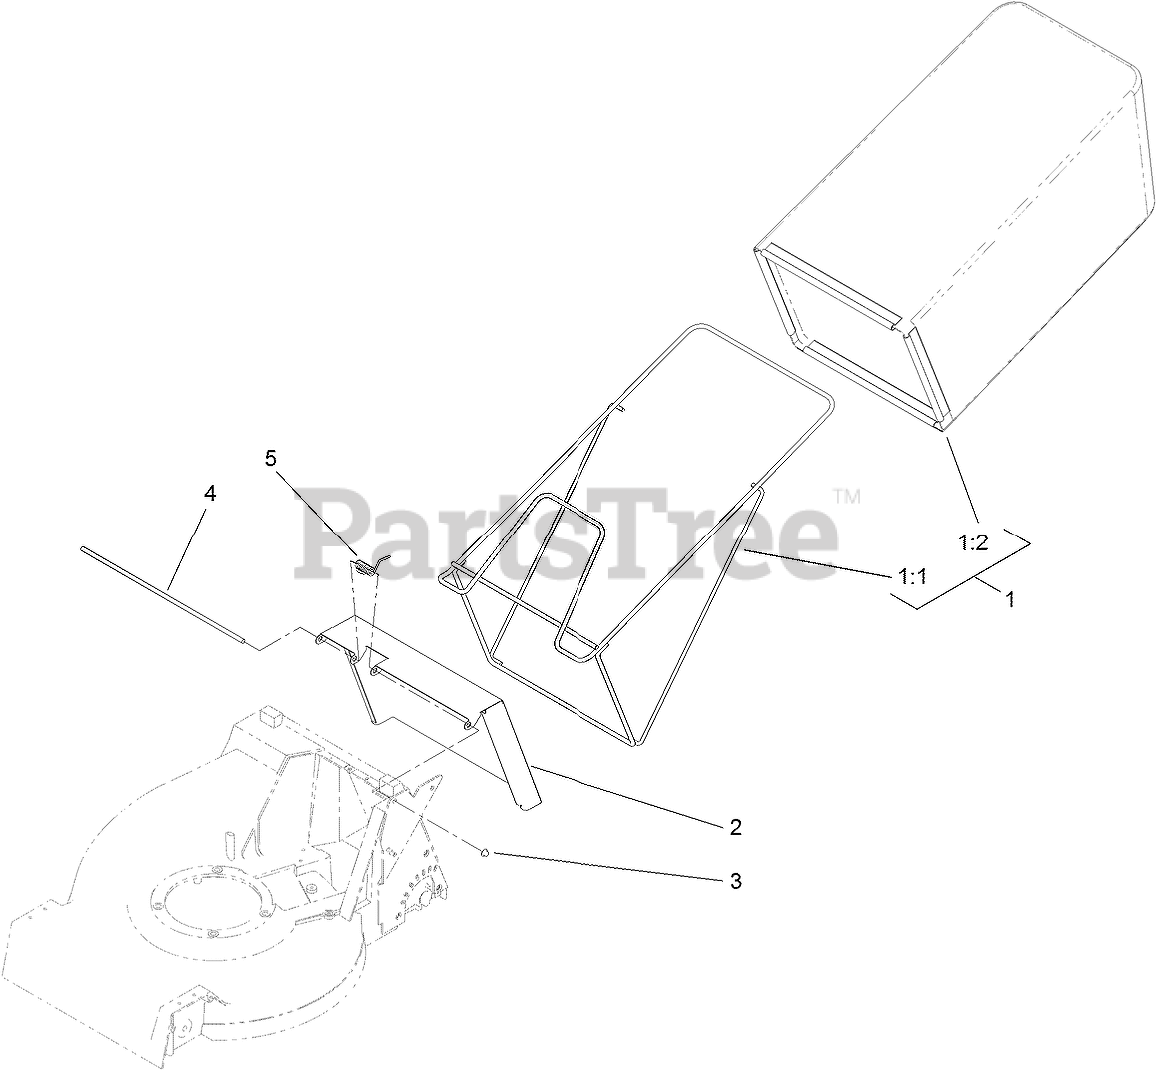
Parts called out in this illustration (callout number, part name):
1	GRASS BAG ASM
1:1	FRAME ASM
1:2	BAG-GRASS
2	DOOR-DISCHARGE, REAR
3	PUSHNUT-CAP, WASHER
4	ROD-DOOR
5	SPRING-TORSION, DOOR
